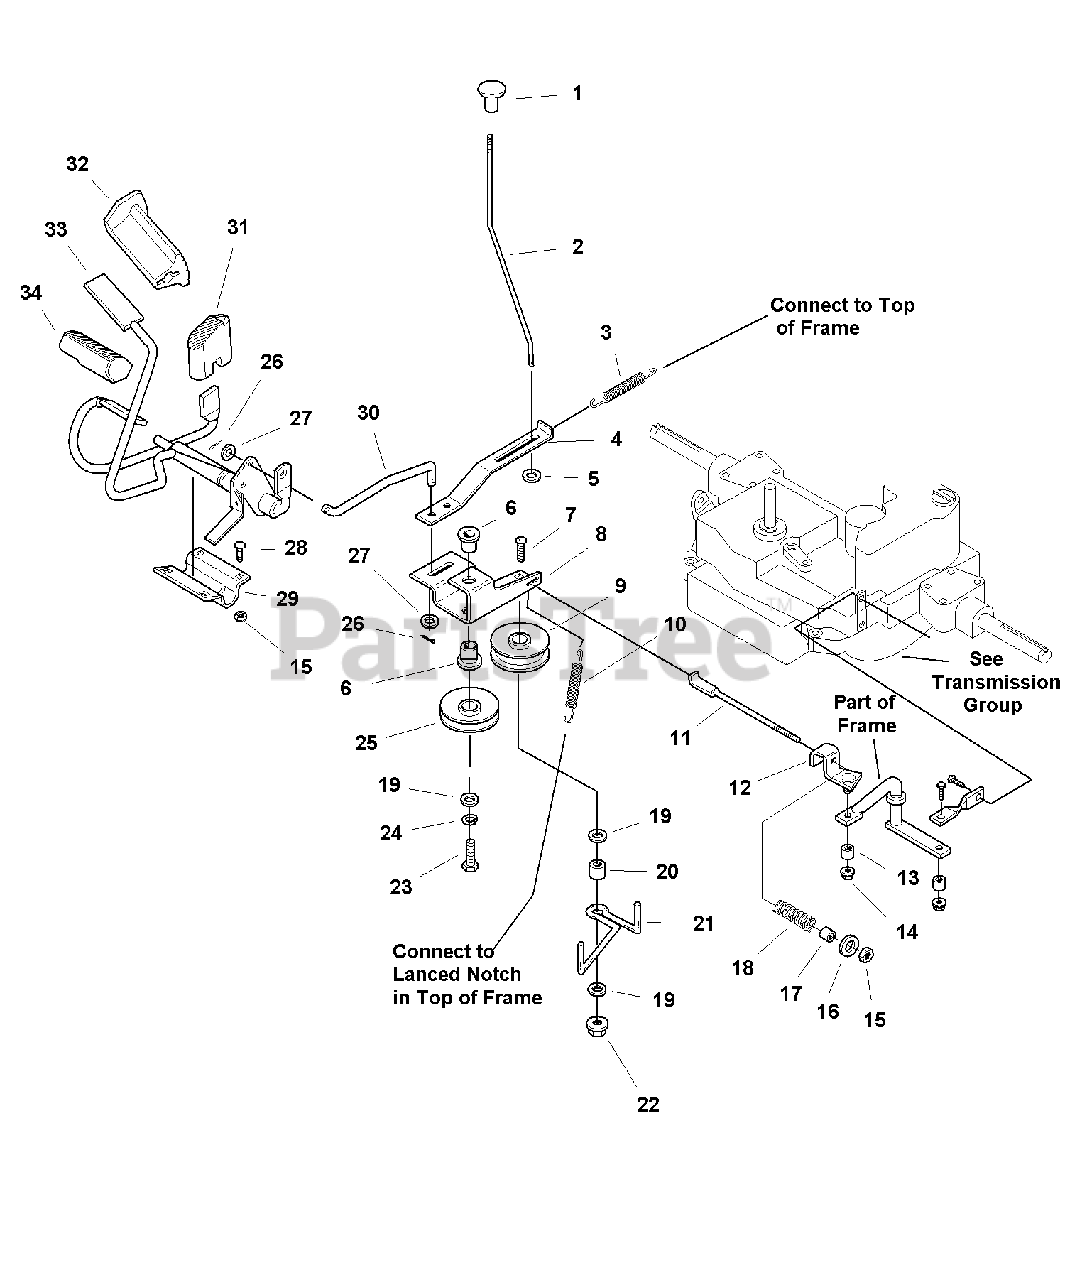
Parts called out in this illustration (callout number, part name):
2	ROD, Parking Brake
3	SPRING, Extension
4	LEVER, Parking
5	WASHER, 1/4
6	BUSHING, 21/32, Nylon
7	CARRIAGE BOLT, 3/8-16 x 2-1/4
9	PULLEY, Backside, Idler, 3-1/4 OD
10	SPRING, Extension
12	GUIDE BELT & STUD ASSEMBLY
14	NUT, Hex Flange, 5/16-18
15	NUT, Hex Lock, 5/16-18
16	WASHER, 5/16
18	SPRING, Compression
19	WASHER, 5/16
22	NUT, Hex Head Whiz Lock, 3/8-16
23	CAPSCREW, Hex Head, 3/8-16 x 1-3/4
24	LOCKWASHER, 3/8
25	PULLEY, Idler, 3 OD
26	PIN, Cotter, 1/8 X 3/4
27	WASHER, 5/16
28	CARRIAGE BOLT, 5/16-18 x 3/4
30	ROD, Clutch
31	PAD, Reverse Pedal
32	PAD, Brake Pedal
33	FOOT PEDAL & BRAKE ARM ASSEMBLY
34	PAD, Forward Pedal
